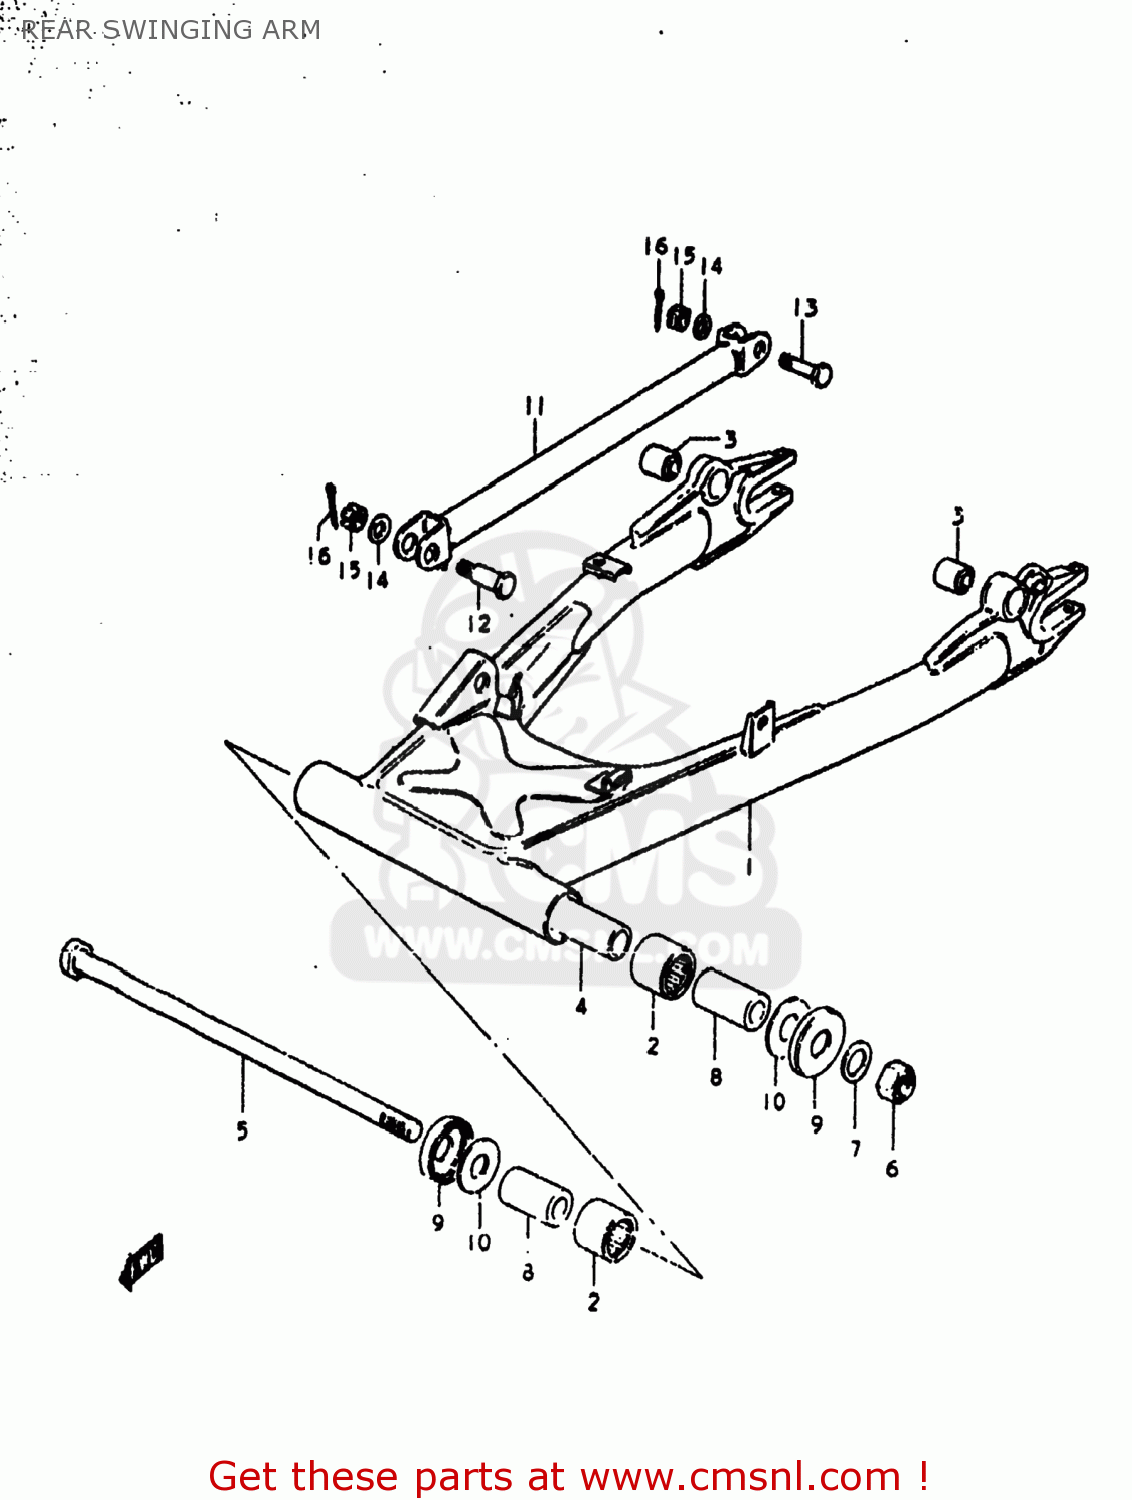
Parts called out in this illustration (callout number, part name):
1	SWING ARM ASSEMBLY,REAR
2	BEARING(25X33X30)
3	BUSH
4	SPACER,RR SWGARM PIVOT CTR
5	SHAFT,REAR SWING ARM
6	NUT 16MM
7	WASHER
8	SPACER,RR SWGARM PIVOT
9	COVER,RR SWGARM DUST SEAL
10	WASHER
11	LINK,REAR TORQUE
12	BOLT
13	BOLT(10X39)
14	WASHER
15	NUT
16	PIN 20X20
